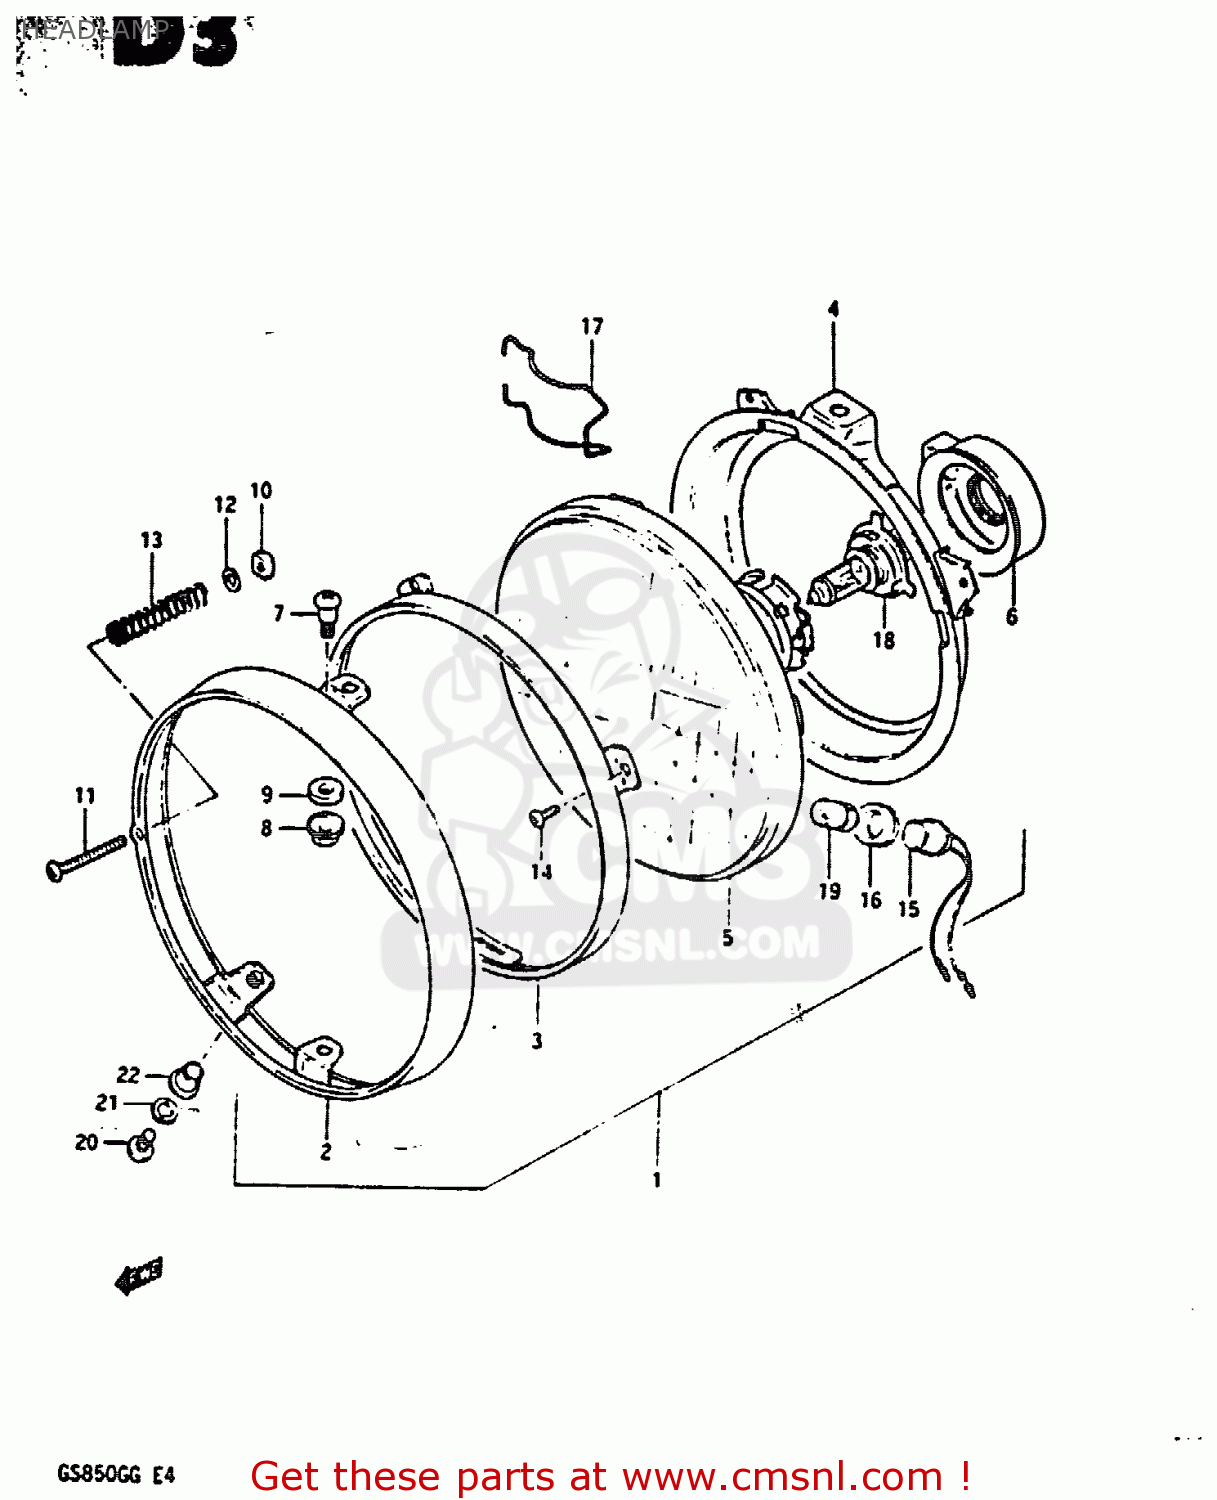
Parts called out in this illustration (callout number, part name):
1	HEADLAMP ASSY
2	RIM
3	RETAINER
4	RING,HEADLAMP UNIT
5	UNIT
6	COVER,HEADLAMP SOCKET
7	SCREW
8	NUT,ADJUSTING
9	SPACER
10	NUT
11	SCREW
12	WASHER
13	SPRING,HEADLAMP ADJUST
14	SCREW
15	SOCKET
16	JOINT,RUBBER
17	CLAMP,HEADLAMP SOCKET
18	BULB(12V60/55W,H4)
19	BULB(12V4W)
20	SCREW
21	WASHER,LOCK
22	WASHER
